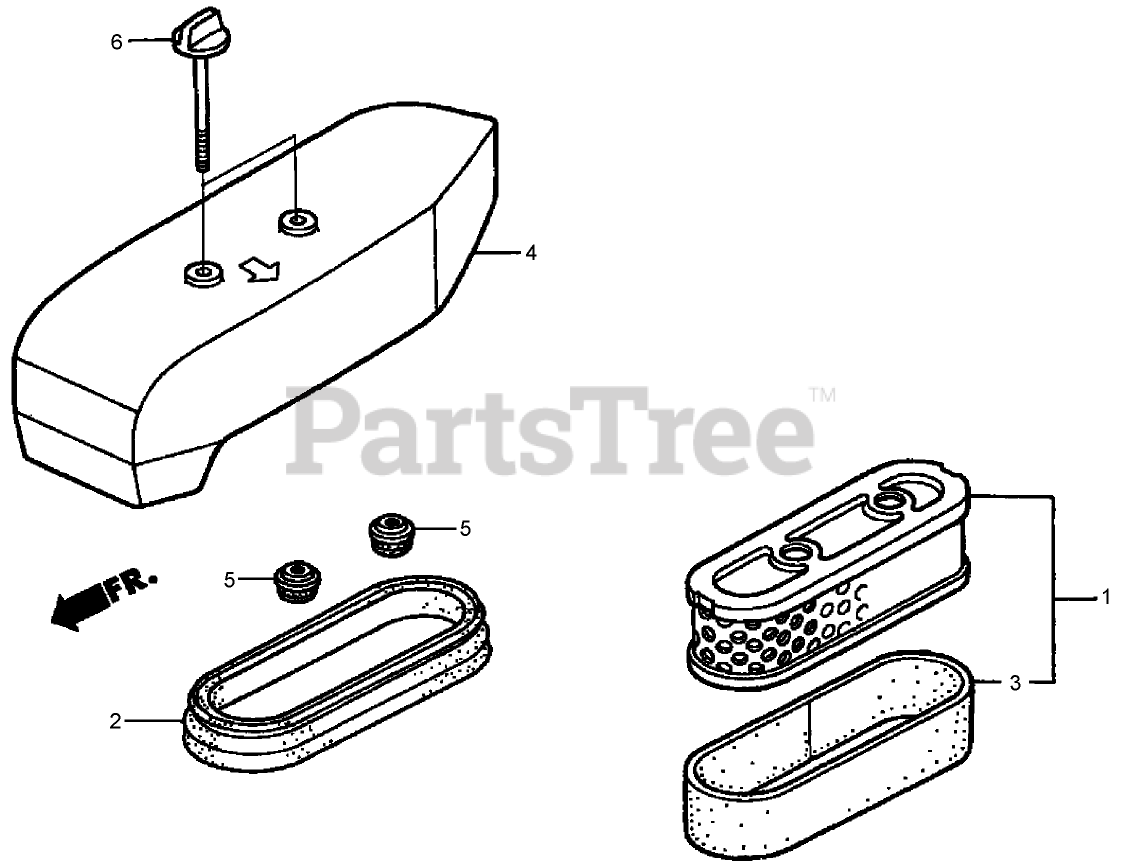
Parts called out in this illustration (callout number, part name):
1	ELEMENT-CLEANER, AIR
2	Gasket-Element
3	Filter (Outer)
4	COVER-CLEANER, AIR
5	GROMMET-CLEANER, AIR
6	BOLT-CLEANER, AIR (6X73)
